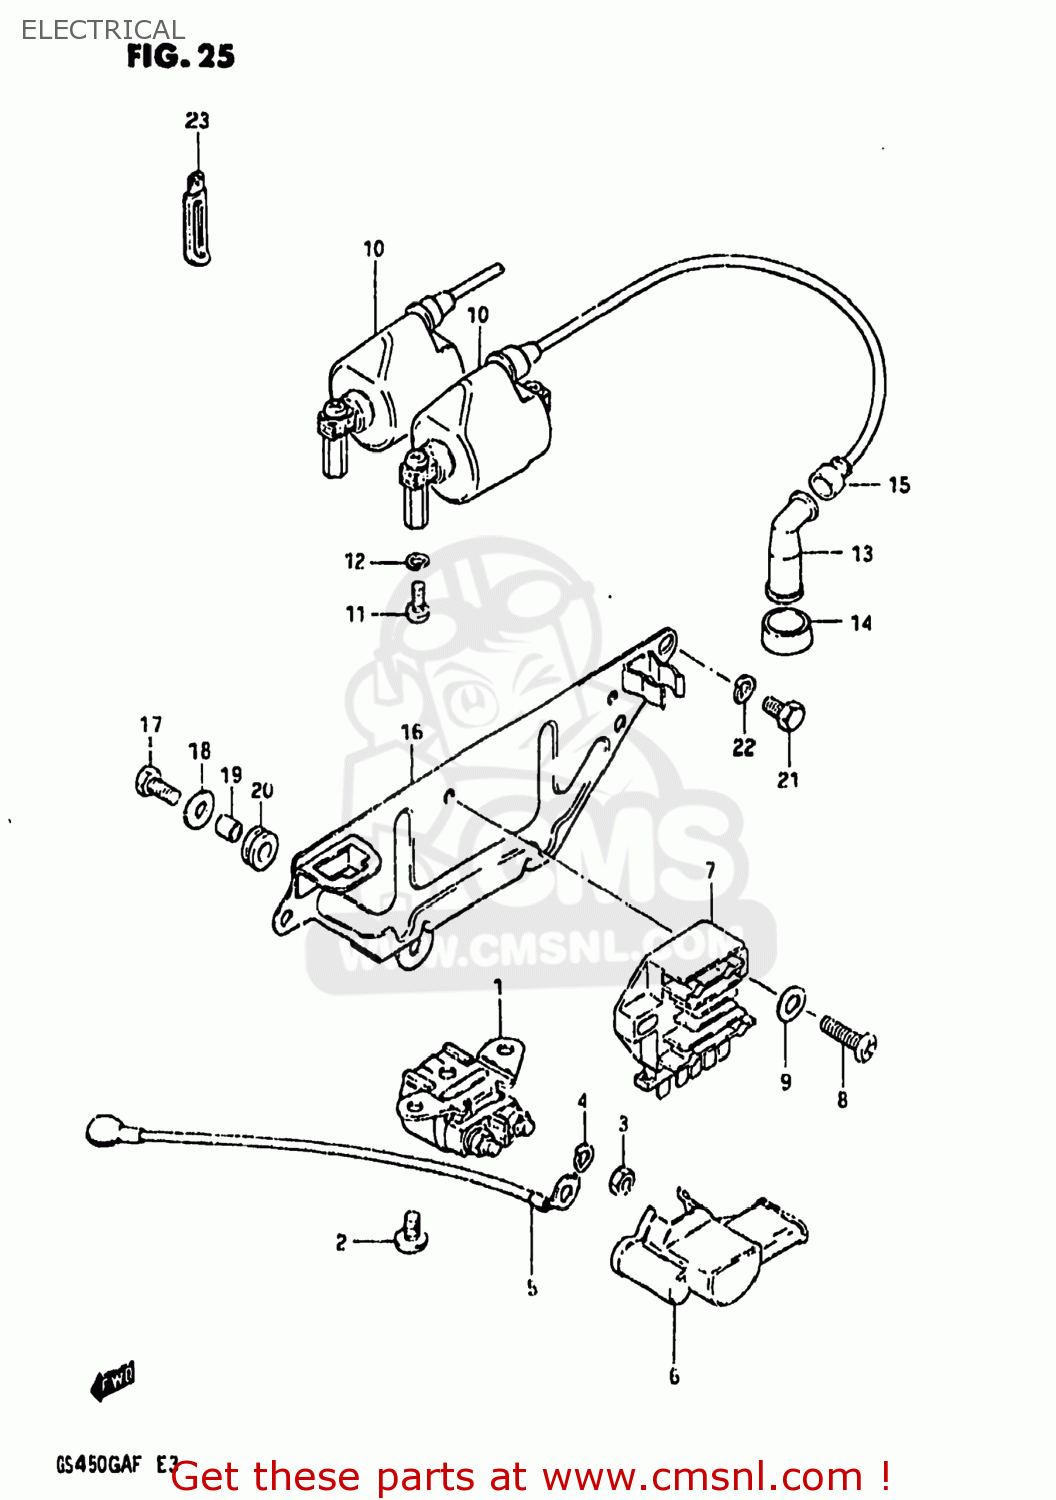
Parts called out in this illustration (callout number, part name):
1	RELAY ASSY,STARTING MOTOR
2	SCREW
3	NUT
4	WASHER,LOCK
5	WIRE,STARTER MOTOR LEAD
6	CAP,STARTER RELAY
7	RECTIFIER ASSEMBLY
8	SCREW
9	WASHER
10	COIL ASSEMBLY,IGNITION
11	SCREW
12	LOCK WASHER
13	CAP,SPARK PLUG
14	SEAL,SPARK PLUG
15	SEAL,SPARK PLU
16	HOLDER COMP,ELECTRONIC PARTS
17	BOLT,M6X1X20
18	WASHER
19	SPACER (6.1X8X9.5)
20	CUSHION
21	BOLT
22	LOCK WASHER
23	CLAMP
